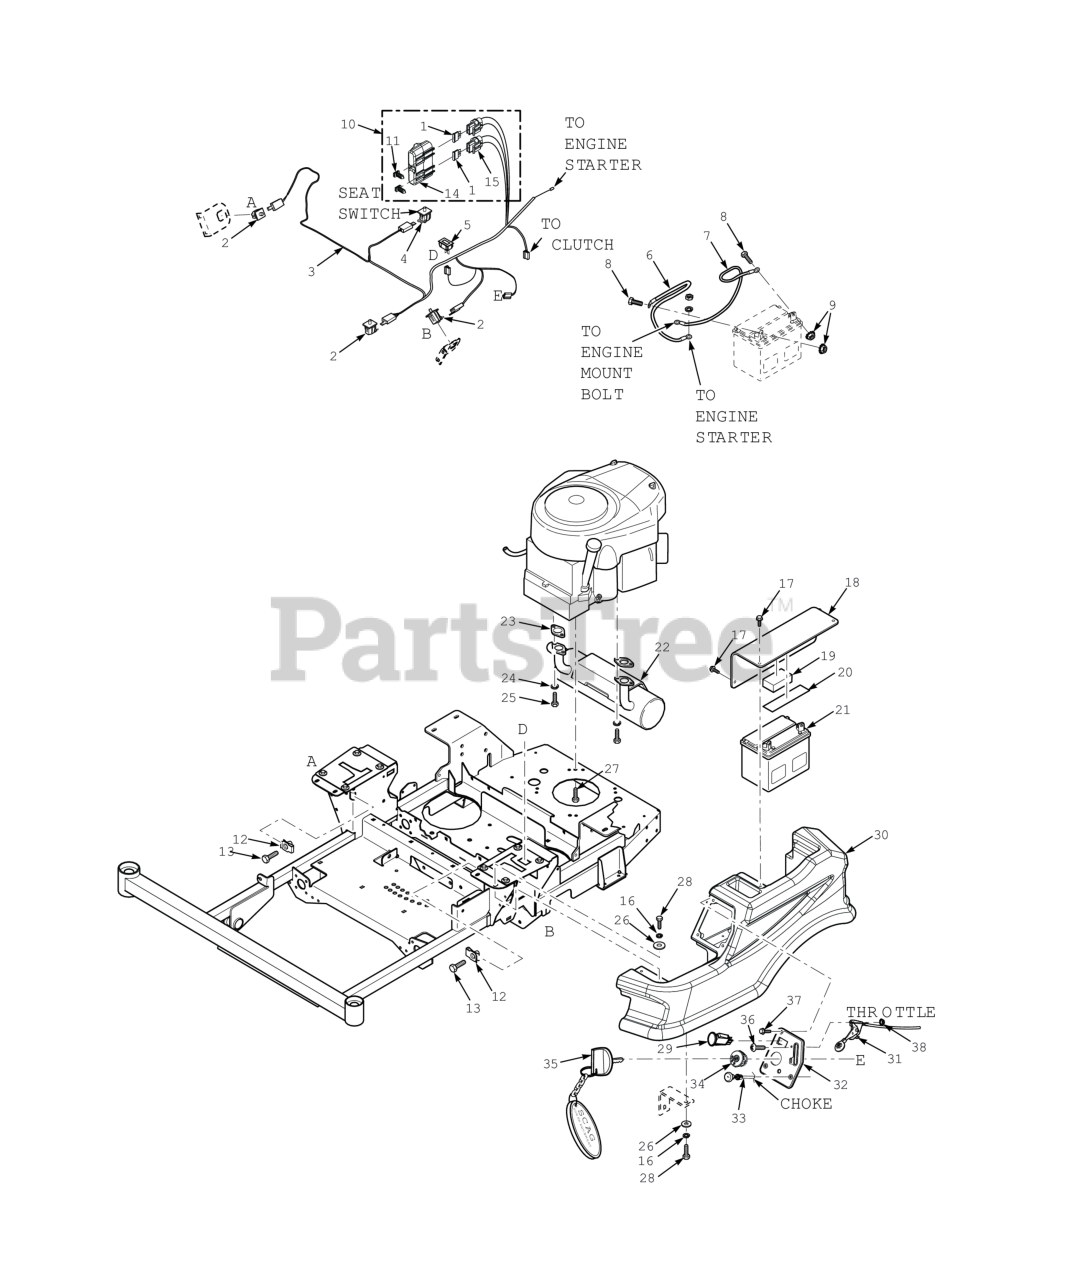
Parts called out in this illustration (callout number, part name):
1	FUSE, 20 AMP BLADE TYPE AUTOMOTIVE
2	Switch, Double Pole - Plunger
3	Wire Harness, Main
4	Switch, Double Pole - Twist
5	Hour Meter, Inductive
6	Battery Cable, 25" Red (Kawasaki)
7	Battery Cable, 27" Black (35BV & 37BV-EFI) - Briggs & Stratton
8	Bolt, Hex Head 1/4-20 x .5" Battery, (Not Available Through Scag)
9	Nut, 1/4 - 20 Hex
10	Double Fuse Assy.
11	Clip, Fuse Holder
12	U-Nut, 3/8-16 (short)
13	Bolt, Hex Head 3/8-16 x 1-1/4" with Thread Lock Patch
14	Cover, Sealed Double
15	Fuse Holder Assembly
16	Lockwasher, 5/16 (.317 x .586 x .078) Helical Spring
17	CAP SCREW, 1/4-20 X 1/2" SERRATED FLANGE HEX
18	Battery Cover (incl. items 19 & 20)
19	Pad, Battery - Rubber
20	Rubber Pad
21	Battery, 350 CCA (not available through Scag)
22	Muffler, Kawasaki FS/FX
23	Battery, 350 CCA
24	Battery, 350 CCA
25	Battery, 350 CCA
26	Flatwasher, 5/16-.375 x .875 x .083 (35BV & 37BV-EFI)
27	Bolt, Hex Head Self-Tap 3/8-16 x 1-1/4" (Kohler x3 - 25EFI, Kohler x4 - 29EFI)
28	BOLT, SERRATED FLANGE HEX HEAD 5/16-18 X 3/4"
29	Switch, PTO - 10 Amp
30	Console, LH - SPZ
31	Throttle Cable, Briggs & Stratton
32	INSTR PANEL W/ DECAL, SFZ
33	Choke Cable, Briggs & Stratton
34	Ignition Switch
35	Key w/Shroud Only
36	Bolt, Carriage #10-24 x 1/2"
37	Screw, Flanged, 5/16-18 x 1/2"
38	Nut, Elastic Stop #10-24
